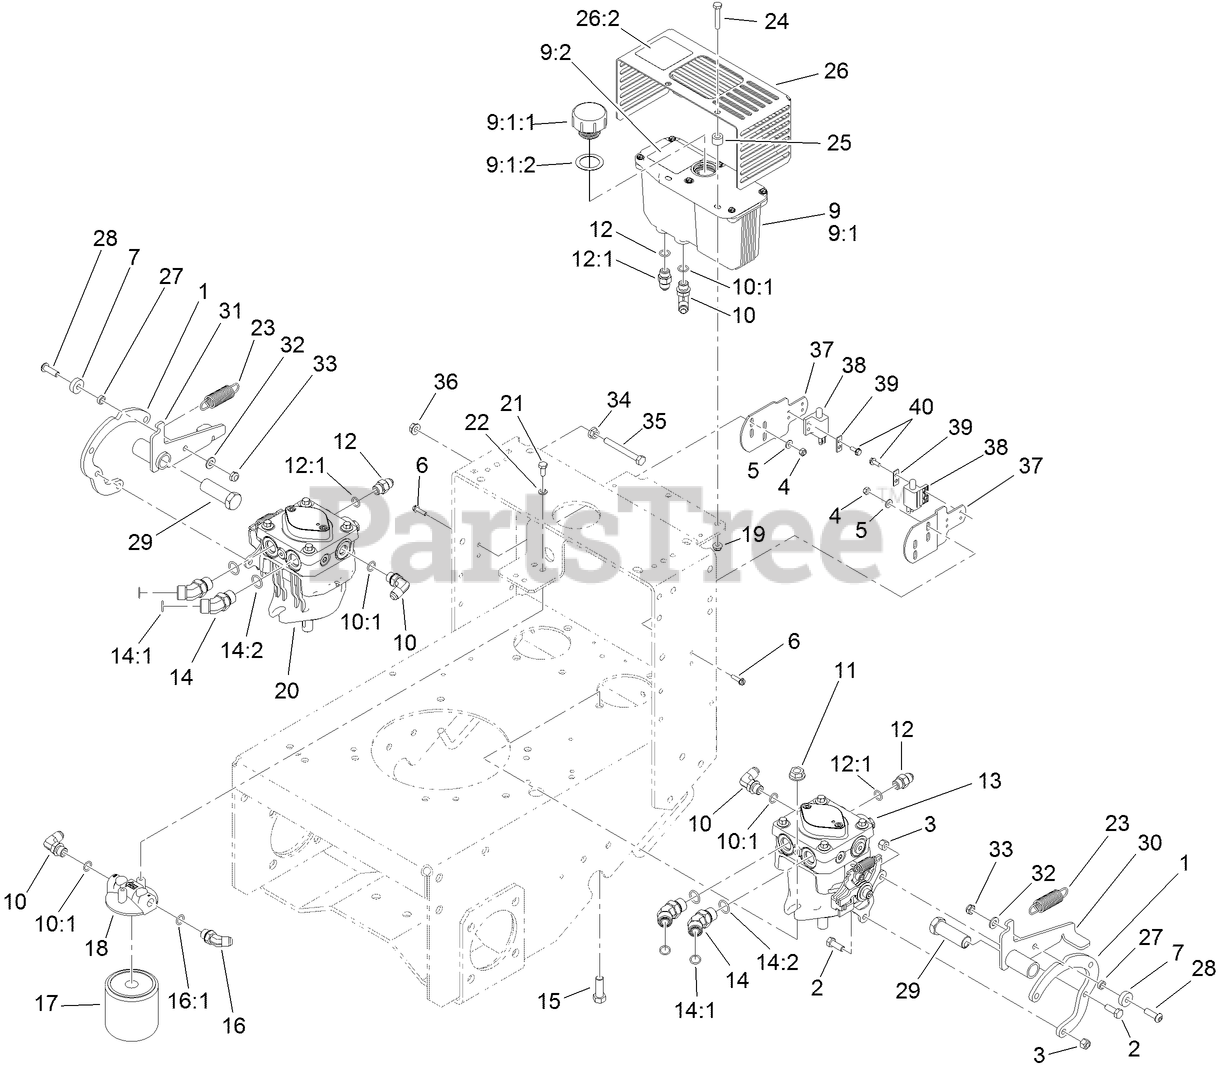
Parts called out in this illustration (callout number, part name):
1	BRACKET-ADAPTER, PUMP
2	SCREW-HH
3	NUT-LOCK, NI
4	NUT-LOCK, NI
5	WASHER-FLAT
6	SCREW-HWH
7	BEARING-BALL
9	HYD RESERVOIR ASM
9:1	Reservoir-HYD
9:1:1	CAP-RESERVOIR, HYD
9:1:2	GASKET-CAP
9:2	DECAL-WARNING
10	FITTING-ELBOW, 90 DEG
10:1	O-RING
11	NUT-HF
12	FITTING-STRAIGHT
12:1	O-RING
13	HYD PUMP ASM
14	FITTING-HYD, 45 DEG
14:1	O-RING
14:2	O-RING
15	SCREW-HH
16	FITTING-ELBOW, 45 DEG
16:1	O-RING
17	FILTER-OIL, HYD
17	FILTER-OIL, HYD (WINTER)
18	HEAD-FILTER
19	NUT-HF
20	HYD PUMP ASM
21	SCREW-HH
22	WASHER-LOCK
23	SPRING-EXTENSION
24	SCREW-HH
25	Spacer
26	SHIELD ASM
26:2	DECAL-WARNING
27	SPACER-BEARING
28	SCREW-HSBH
29	PIN-ADJUSTMENT, NEUTRAL
30	LH DETENT ARM ASM
31	RH DETENT ARM ASM
32	WASHER-PLAIN
33	NUT-LOCK, NI
34	NUT-HHF, SMOOTH
35	SCREW-HH
36	NUT-HF
37	BRACKET-NEUTRAL
38	SWITCH-CLOSED, NORMALLY
39	PLATE-SWITCH
40	SCREW-TAPTITE
